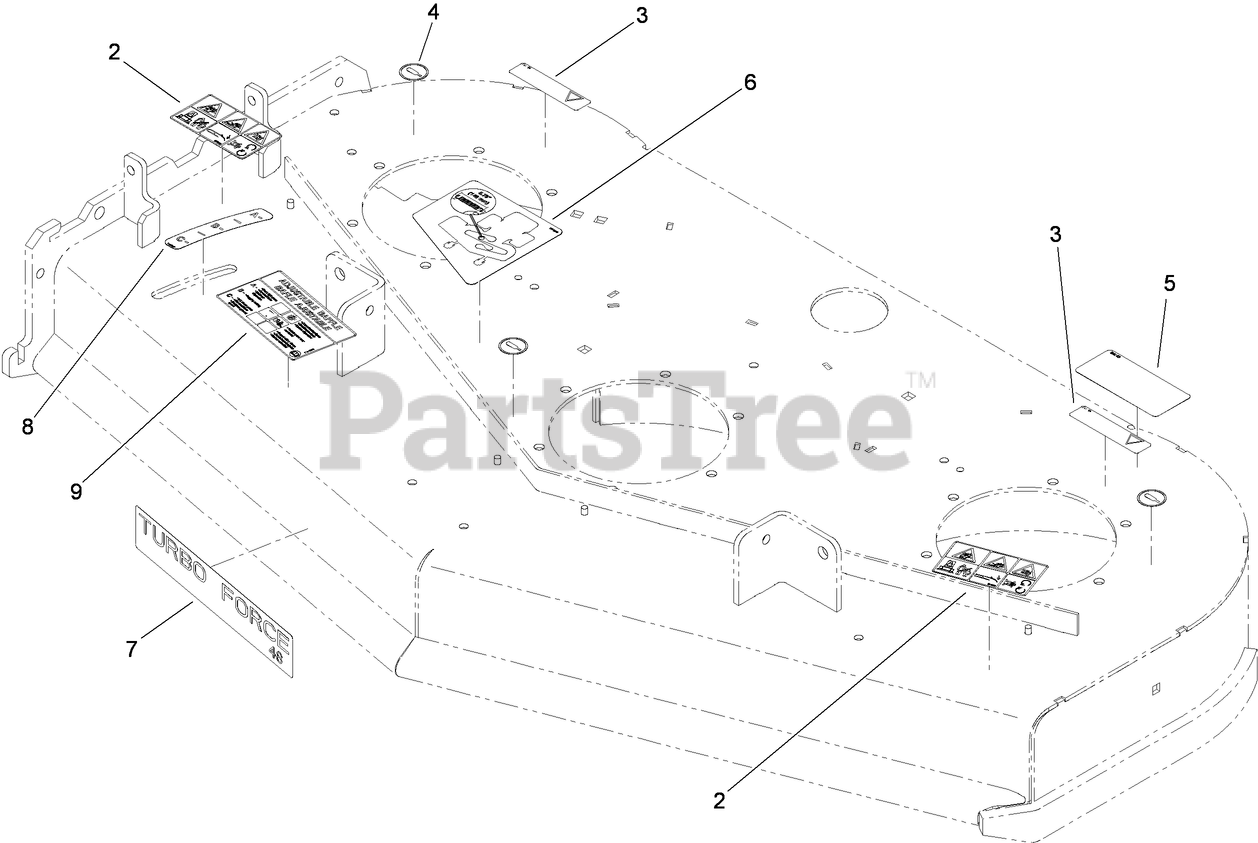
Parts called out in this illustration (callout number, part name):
2	DECAL-DANGER
3	DECAL-WARNING
4	DECAL-GREASE
5	DECAL-TORQUE, BLADE BOLT
6	DECAL-BELT ROUTING, CE
8	DECAL-SETTING, BAFFLE
9	DECAL-ADJUSTMENT, BAFFLE
